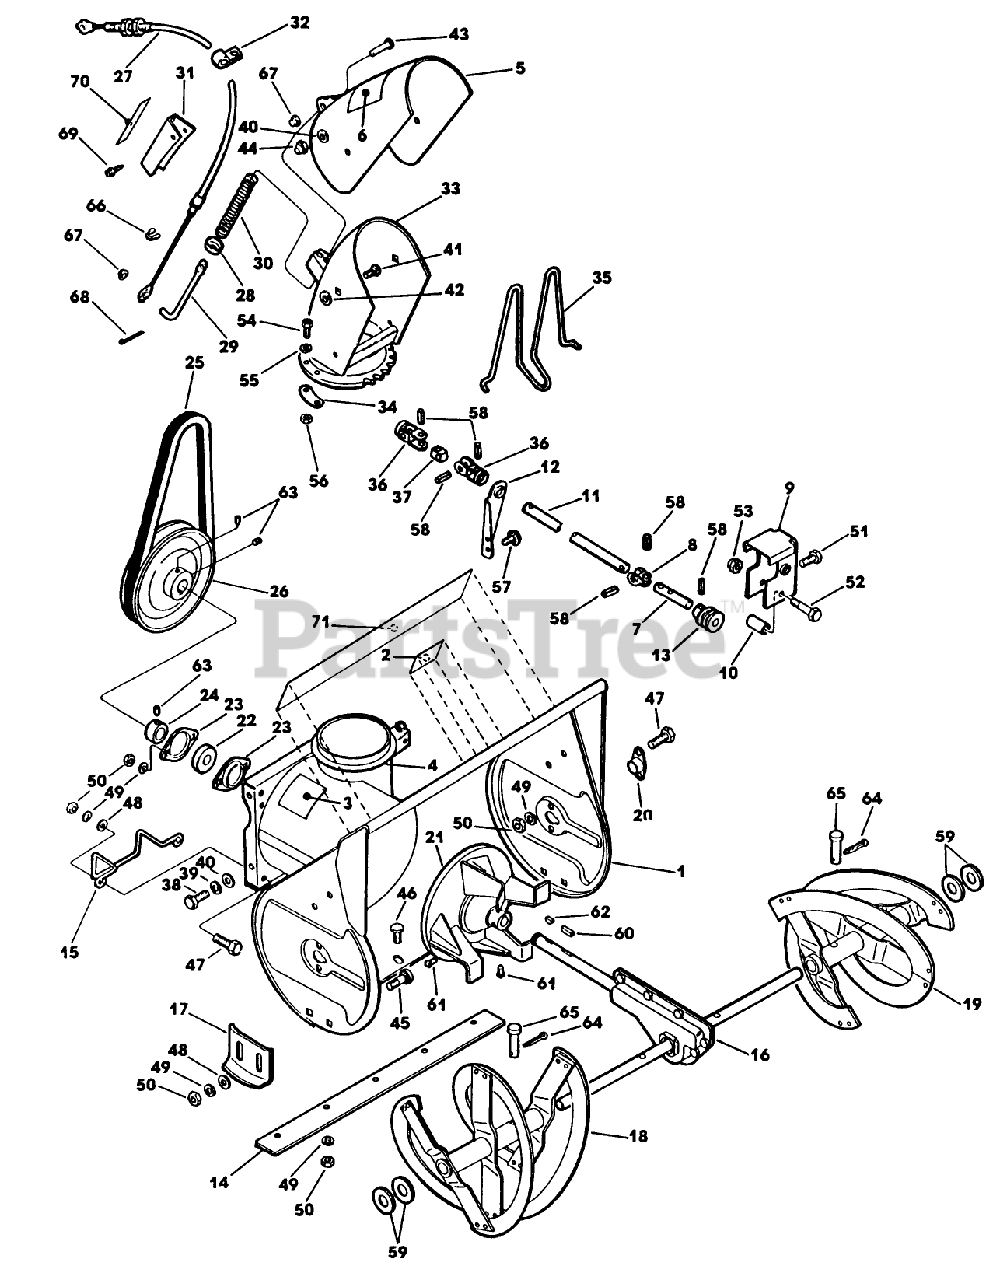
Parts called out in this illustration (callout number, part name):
14	SCRAPER BLADE *B
15	LWR AUGER BELT GUIDE
18	AUGER ASSEM R/B 744444
19	LH AUGER AY
22	DISCONTINIUED
23	FLANGETTE-BEARING
24	COLLAR-BEARING
25	V-BELT
26	PULLEY ASM
34	HOLD DOWN CHUTE
37	PIVOT PIN
39	WASHER
40	WASHER
44	NUT-LOCKING
45	BOLT - CARRIAGE
47	SCREW - HEX
50	NUT SS
53	NUT-LOCK, CONE
54	SCREW
55	WASHER - LOCKING
57	SCREW-HWH
59	WASHER
62	KEY
63	SET SCREW
65	PIN-SHEAR
66	RET. RING
69	SCREW S
